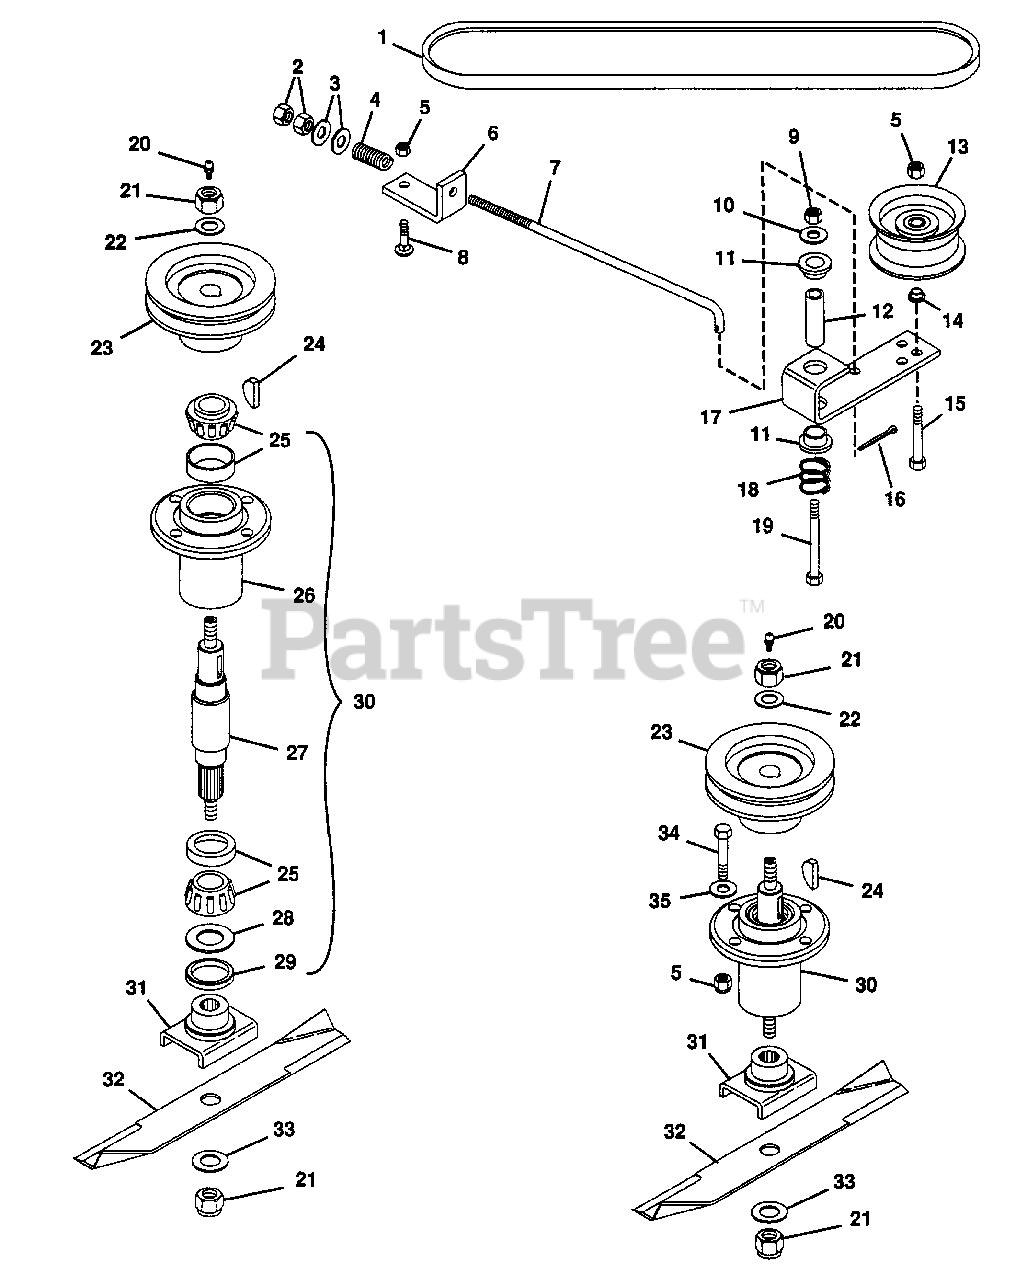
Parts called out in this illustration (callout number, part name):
1	Belt, Pro-36 Mower
2	Nut, Hex 3/8-24
3	Washer, Flat .406x.812x.065
4	Spring, Comp. 1x.78x338 Lb/N
5	Nut, Lock 3/8-16
6	Bracket, Belt Tensioner
7	Rod, Idler
8	Bolt, 3/8-16x1.00 Rd Hd Sq Nk
9	Nut, Lock 1/2-13
10	Washer, Flat .531x1.250x.100
11	Bushing, Flange Nylon
12	Bushing, St. .560x.750x2.44 Stl.
13	Pulley, Idler
14	Bushing, Flange Bronze
15	Bolt, Hex 3/8-16x2.25
16	Pin, Cotter .09x.75
17	Arm, Idler Pivot
18	Spring, Comp. 1x.80x36 Lb/N
19	Bolt, Hex 1/2-13x3.25
20	Fitting, Lube 1/8
21	Nut, Lock 5/8-11
22	Washer, Flat .687x1.312x.122
23	Sheave, Spindle
24	Key, Woodruff 1/4x1 Hard #15
25	Assembly, Bearing
26	Housing, Bearing
27	Shaft, Spindle
28	Washer, Flat .975x1.970x.030
29	Seal, Steel
30	Assembly, Spindle
31	Weldment, Blade Cradle
32	Blade, 36" Mower
33	Washer, Flat .656x1.312x.095
34	Bolt, Hex 3/8-16x1.25
35	Washer, Flat .438x1.000x.083
